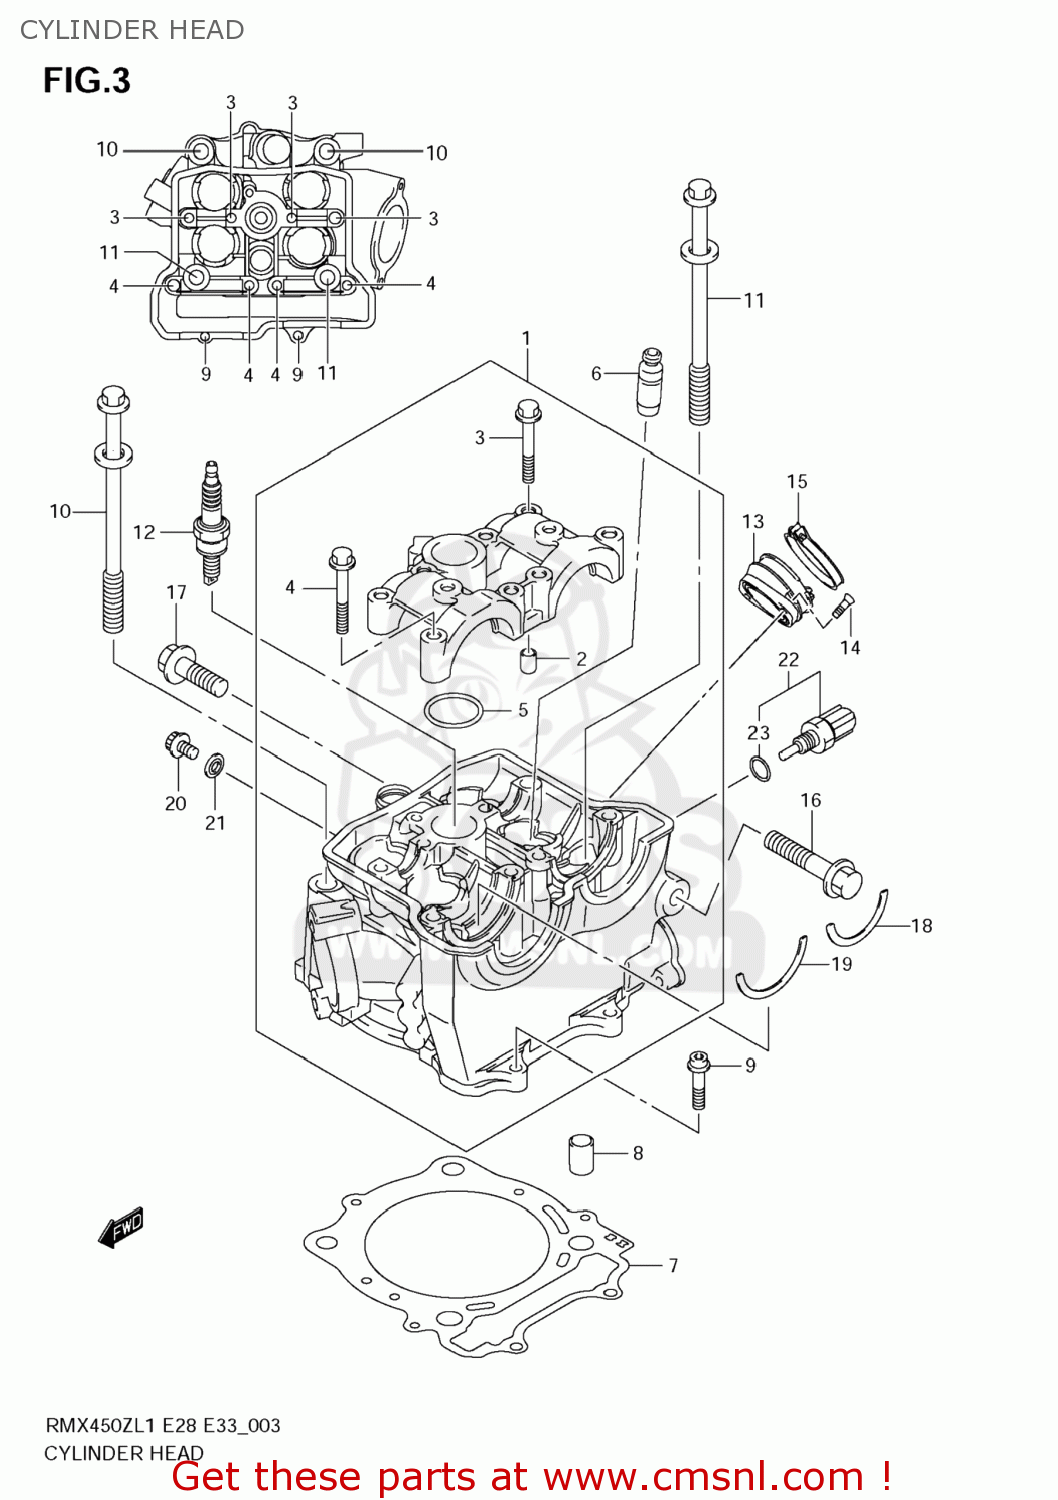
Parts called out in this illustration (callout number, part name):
1	HEAD ASSY,CYLINDER
2	PIN(6.2X8X11)
3	BOLT(6X40)
4	BOLT(6X45)
5	O RING(D:2.4,ID:25.7)
6	GUIDE,VALVE(OS:0.3)
7	GASKET,CYLINDER HEAD (NAS)
8	PIN
9	BOLT
10	BOLT,CYLINDER HEAD(L:140)
11	BOLT,CYLINDER HEAD(L:120)
12	PLUG,SPARK(CR8EIB-10)
13	PIPE ASSY,INTAKE
14	SCREW
15	CLAMP,INTAKE PIPE
16	BOLT(10X43)
17	BOLT(10X30)
18	C RING,CAMSHAFT
19	C RING,CAMSHAFT
20	BOLT
21	GASKET(5.8X13X1.2) (NAS)
22	SENSOR,WATER TEMP
23	O RING
